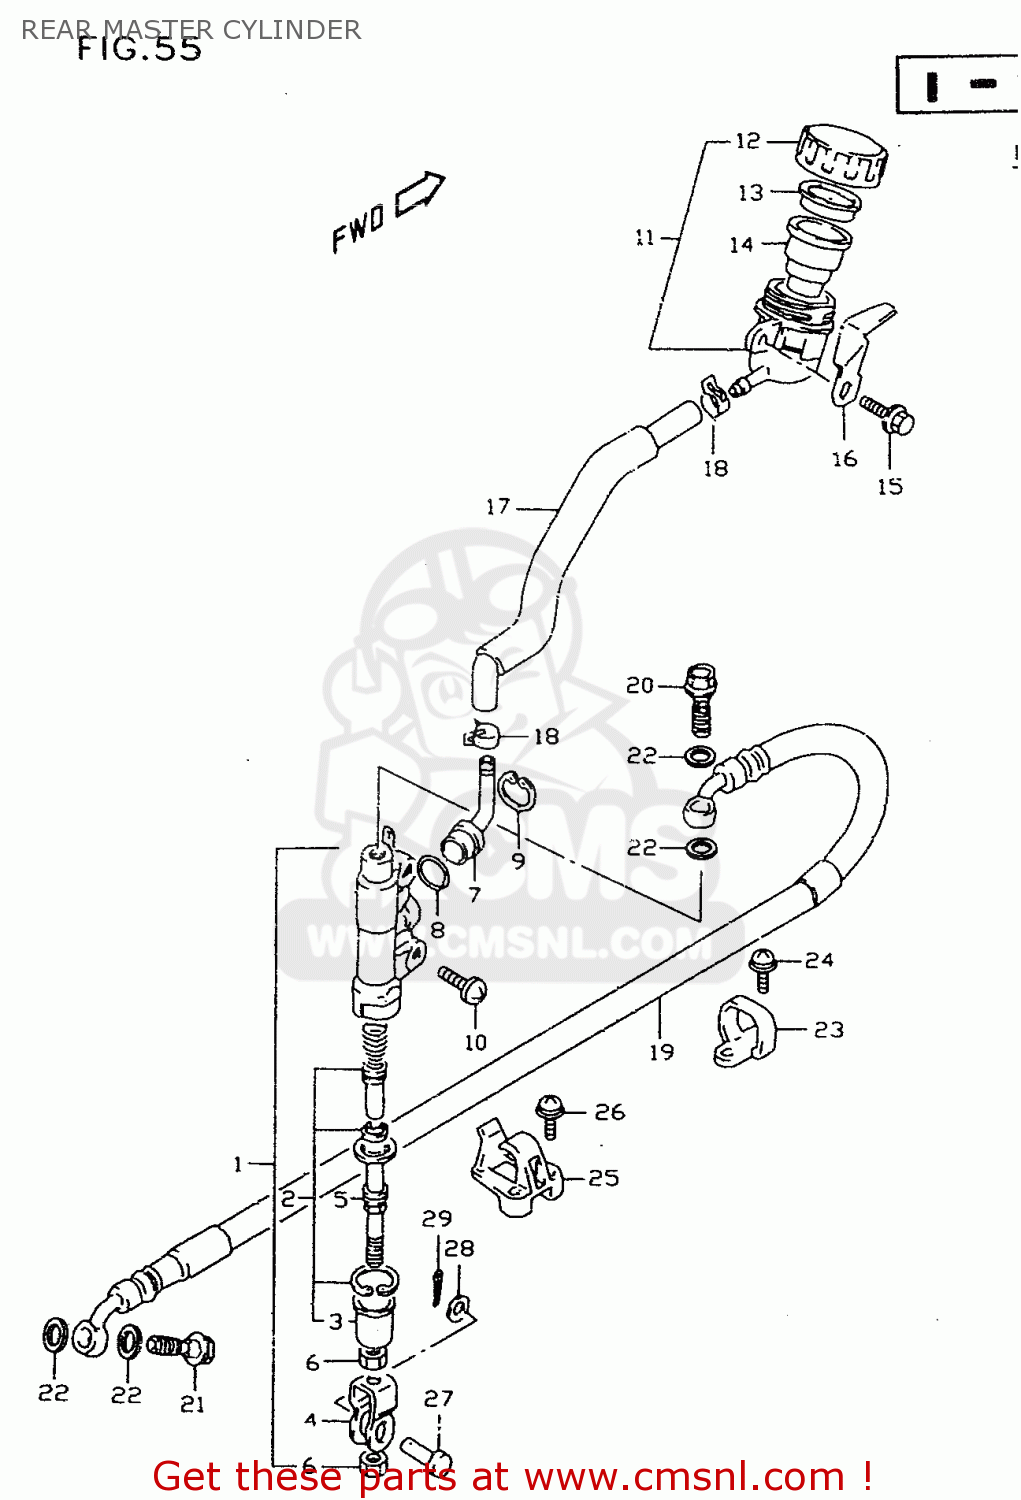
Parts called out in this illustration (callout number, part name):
1	CYLINDER ASSY,RR MASTER
2	PISTON/CUP SET
3	BOOT
4	YOKE
5	ROD,PUSH
6	NUT
7	CONNECTOR
8	O RING
9	CIRCLIP
10	SCREW
11	TANK ASSY,RR BRAKE RESERVOIR
12	CAP
13	PLATE
14	DIAPHRAGM
15	BOLT
16	GUARD,RSVR TANK CAP
17	HOSE COMP,RESERVOIR TANK
18	CLIP
19	HOSE,RR BRAKE
20	BOLT UNION
21	BOLT UNION
22	WASHER(10X15X1.5)
23	GUIDE,RR BRAKE HOSE
24	SCREW
25	GUIDE,RR BRAKE HOSE
26	SCREW
27	PIN(8X20)
28	WASHER(8.5X13X1.6)
29	PIN 20X15
